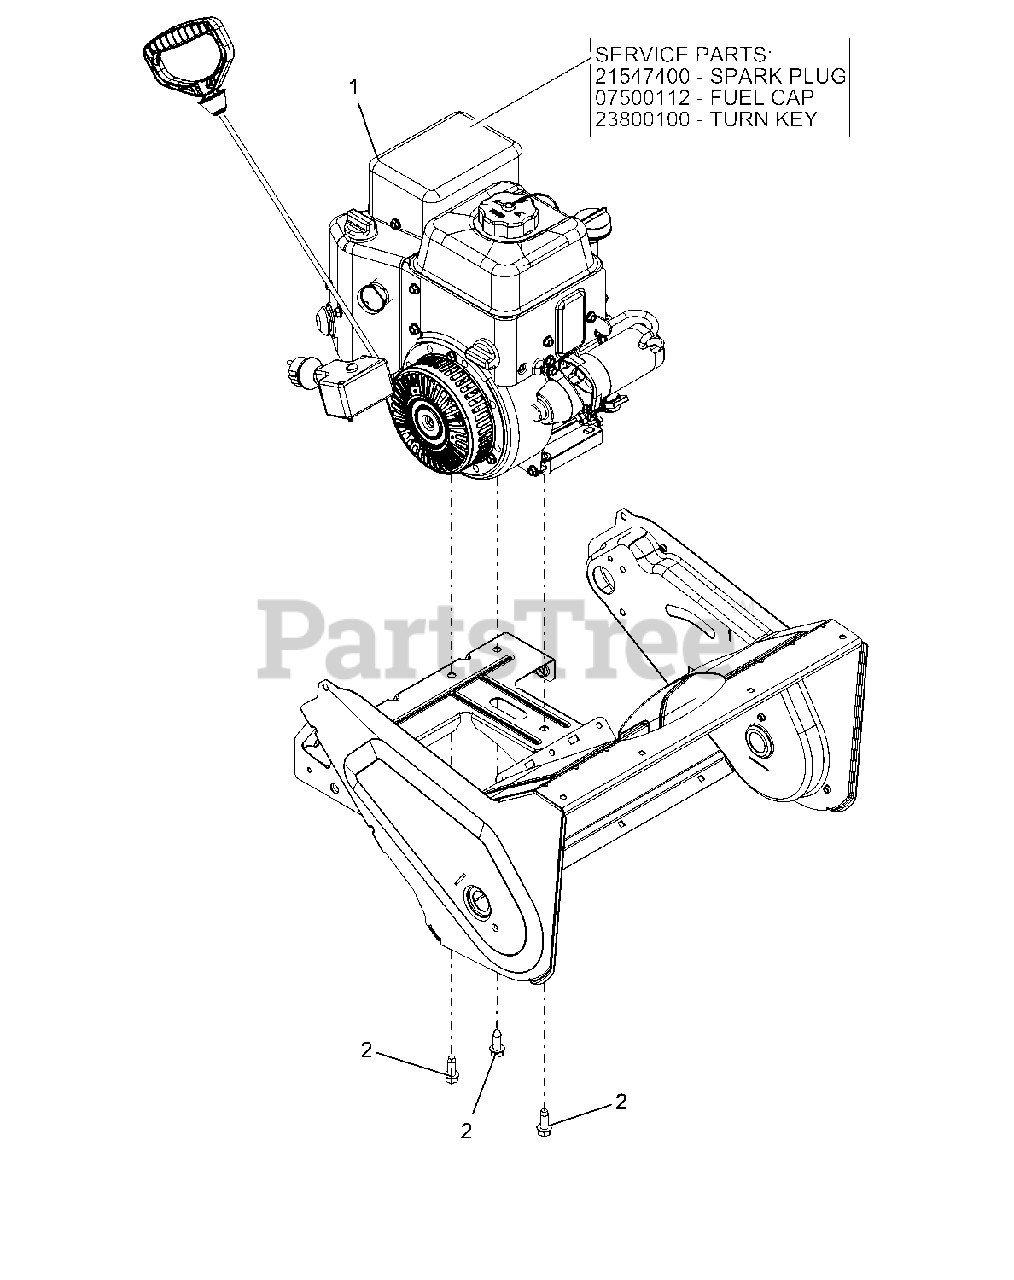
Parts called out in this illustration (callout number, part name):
1	PLUG, SPARK
1	CAP, FUEL TANK BLACK
1	KEY, TURN LCT (2/PACKAGE)
1	ENGINE, ARIENS AX208 ES CE
2	@SCR-TAP .38-16X1.00 HWH TR YZ
